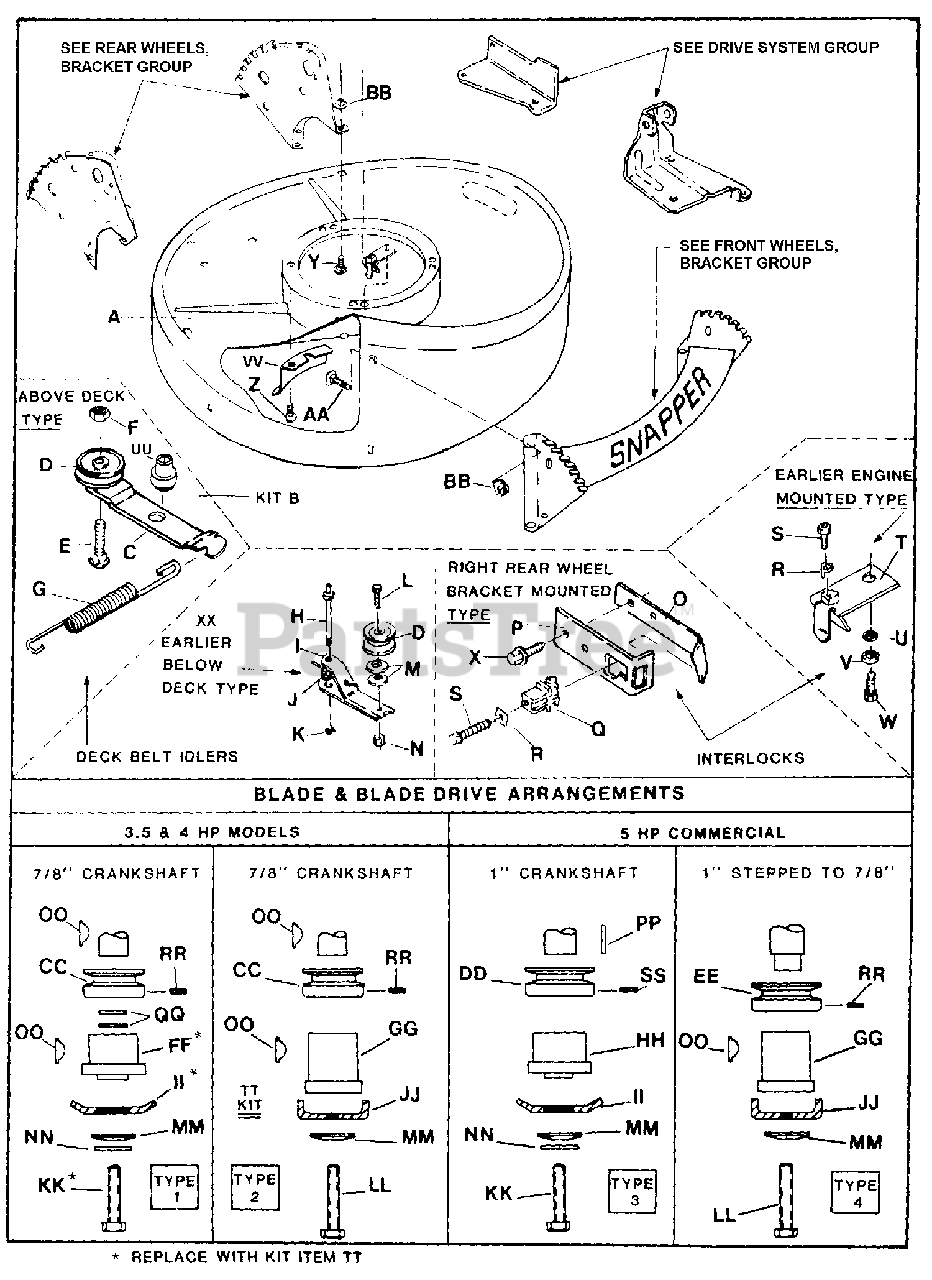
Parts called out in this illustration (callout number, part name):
A	DECK, ALL 21"
B	KIT, ABOVE DECK IDLER
C	ARM, ABOVE DECK IDLER
D	PULLEY, IDLER
E	BOLT, 1/4C x 1-1/4 CARRIAGE
F	NUT, 1/4C HEX Lock
G	SPRING, IDLER ARM to WHEEL BRACKET
H	STUD, IDLER -- MANUAL START MODELS
I	ARM, BELOW DECK TYPE IDLER
J	SPRING, BELOW DECK IDLER
K	RING, RETAINING
L	SCREW, 1/4-28 x 1-1/2 HEX HEAD CAP
M	WASHER, 1/4 SAE
N	LOCKNUT, 1/4-28
O	SPRING, WHEEL BRACKET TYPE INTERLOCK
P	BRACKET, WHEEL BRACKET TYPE INTERLOCK
Q	INSULATOR, INTERLOCK
R	LOCKWASHER, #8 INTERNAL TOOTH TAB
S	SCREW, #8-18 x 3/4 SHEET METAL SELF TAPPING
T	INTERLOCK ASSEMBLY
U	RETAINER, 5/16 BOLT
V	WASHER
W	SCREW, 5/16F x 1-1/2 HEX HEAD CAP
X	SCREW, 1/4 x 3/8 HEX HEAD SELF TAPPING
Y	BOLT, 5/16C x 1/2 SHORT NECK CARRIAGE GR. 5
Z	BOLT, ENGINE MOUNTING 3/8C x 1 WASHER HD SELF TAPPING
AA	BOLT, 5/16C x 1 SHORT NECK CARRIAGE
BB	NUT, 5/16C HEX FLANGE
CC	PULLEY, FOR ALL 3.5 & 4 HP ENGINES 7/8" ID
DD	PULLEY, FOR EARLY 5 HP COMMERCIALS 1" ID
EE	PULLEY, FOR 5 HP WITH STEPPED SHAFTS 1" ID
FF	HUB, BLADE DRIVE 7/8" (TYPE 1)
GG	HUB, BLADE DRIVE 7/8" (TYPE 2 & 4)
HH	HUB, BLADE DRIVE 1" (TYPE 3)
II	BLADE, CUTTING (20.75", .876 Center Hole)(TYPES 1 &, 3)
JJ	BLADE, CUTTING (TYPES 2 &, 4)
KK	SCREW, 3/8-24 x 1-3/4 GRADE 5 CAP
LL	SCREW, 3/8-24 x 2 GRADE 5 CAP
MM	WASHER, CONE
NN	WASHER, FLAT
OO	KEY, 5/32 x 5/8 HI-PRO
PP	KEY, 1/4 SQUARE x 1.44"
QQ	WASHER, 1/2 SPLIT LOCK (USED AS SHIMS)
RR	SETSCREW, 5/16C x 5/16
SS	SETSCREW, 1/4C x 5/16
TT	KIT, BLADE & DRIVE
UU	BUSHING, Idler Arm/Drive Disc
VV	COVER, Belt Hole (Push Models)
XX	KIT, Idler Arm Assy. (Early Below Deck Type)
